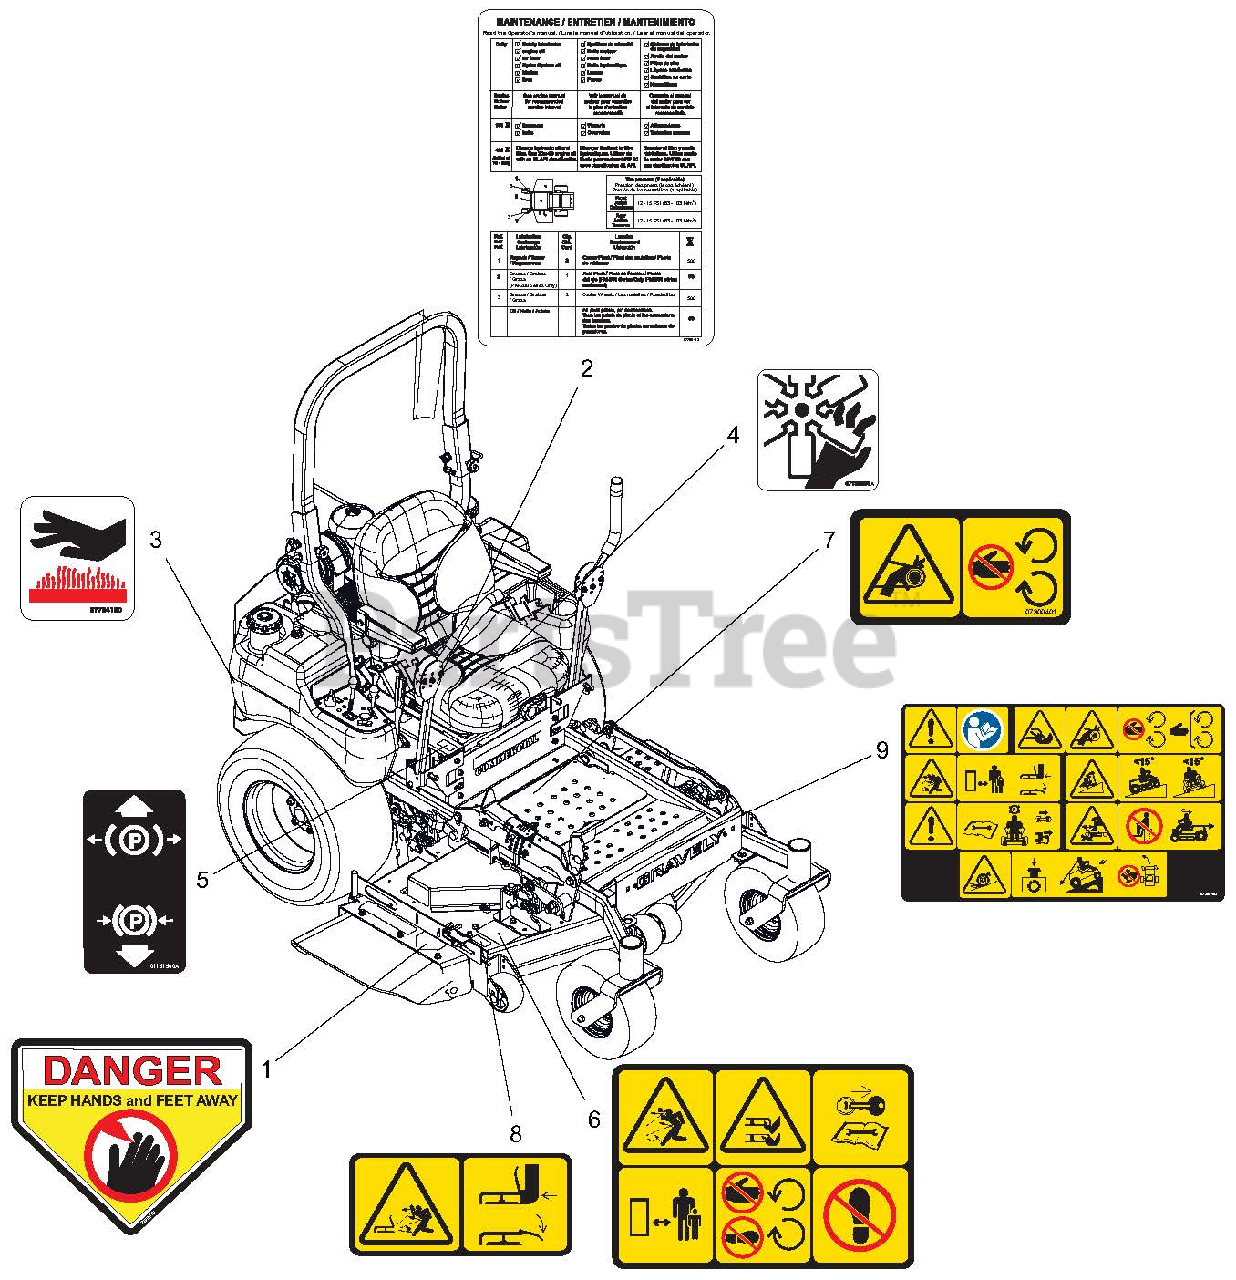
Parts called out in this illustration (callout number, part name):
1	DECAL, DANGER
2	DECAL, MAINT
3	DECAL HOT SURFACE
4	DECAL, DANGER - FAN
5	DECAL, PARKING BREAK LEVER
6	DECAL, SAFETY - MOWER DECK
7	DECAL, SAFETY - GUARDING
8	DECAL, SAFETY - DECK GUARDING
9	DECAL, MAIN SAFETY, COMMERCIAL
